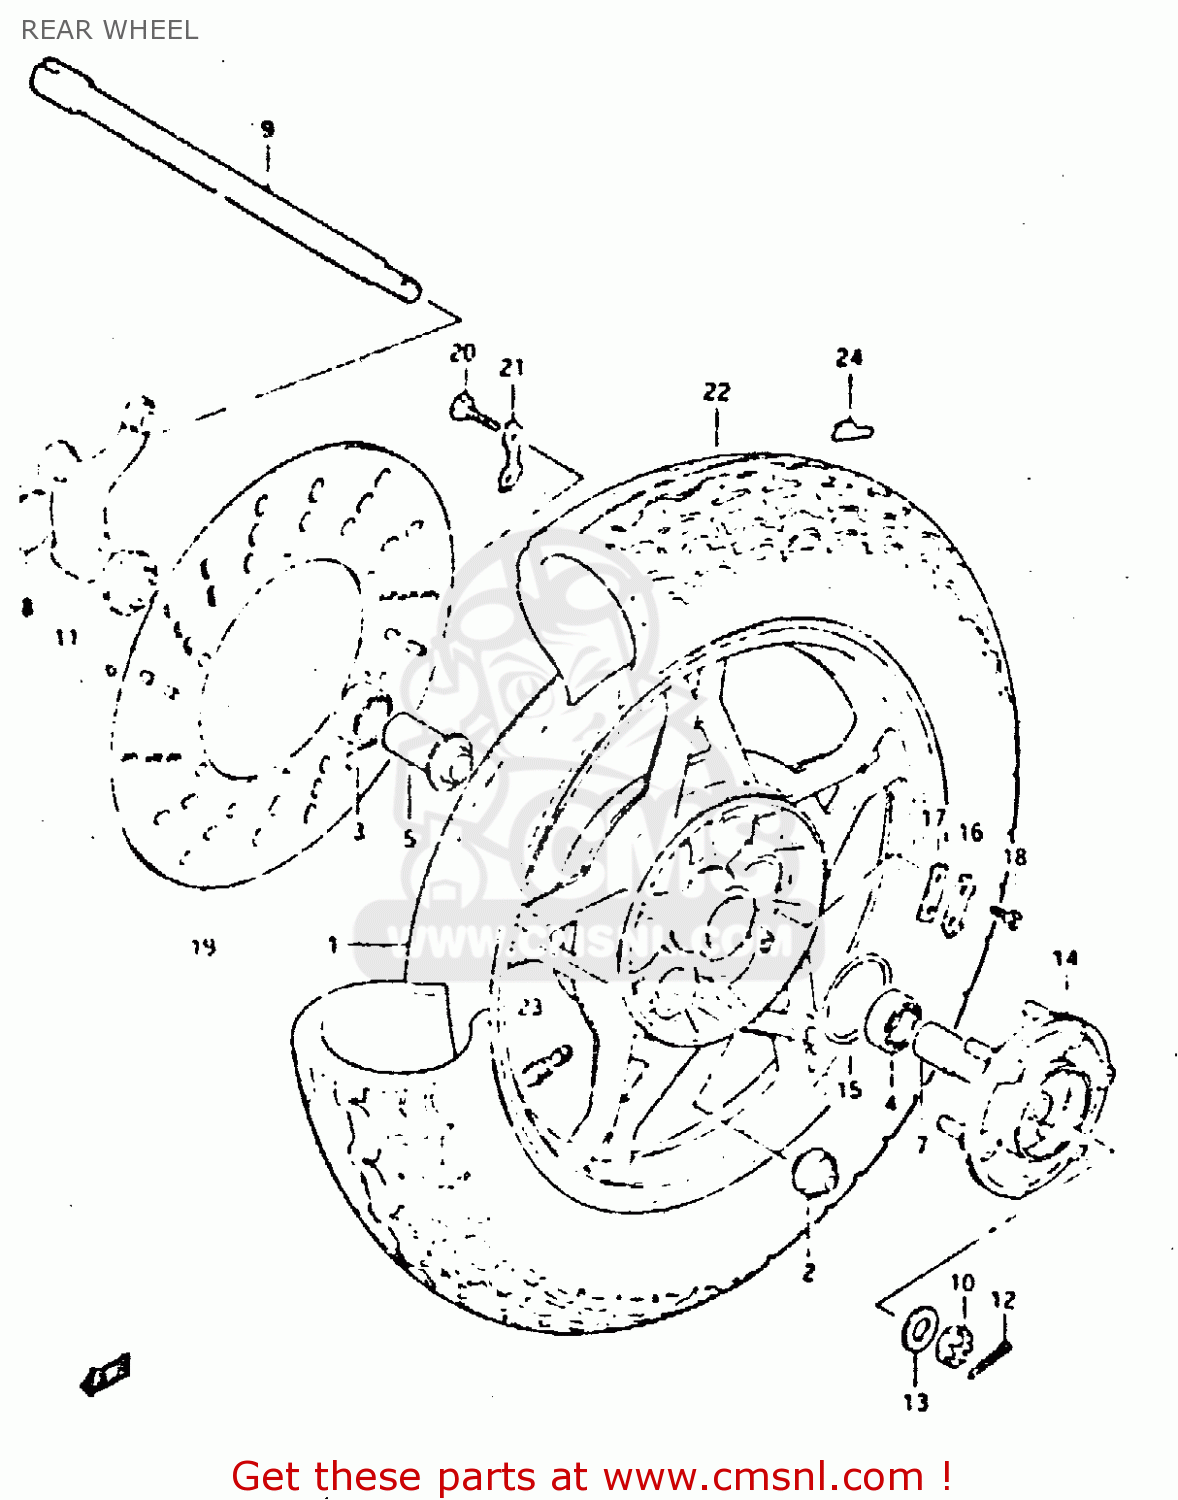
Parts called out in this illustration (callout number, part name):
1	CASTING WHEEL,REAR 2.50
2	BUSH
3	BEARING
4	BEARING
5	SPACER,REAR HUB BEARING
6	SPACER,REAR AXLE
7	SPACER,REAR AXLE,LEFT
8	SPACER,REAR AXLE,RIGHT
9	AXLE,REAR
10	NUT
11	BRACKET,RR,CALIPER
12	PIN,COTTER
13	WASHER(16.5X36X3.2)
14	JOINT ASSEMBLY,REAR HUB DRUM
15	O RING(D:2.1,ID:65)
16	WASHER
17	WASHER,THRUST(T:1.6)
18	BOLT(6X16)
19	DISC,RR BRAKE
20	BOLT(8X25)
21	WASHER
22	TIRE
23	VALVE ASSEMBLY,WHEEL RIM,J
24	BALANCER,WHEEL
